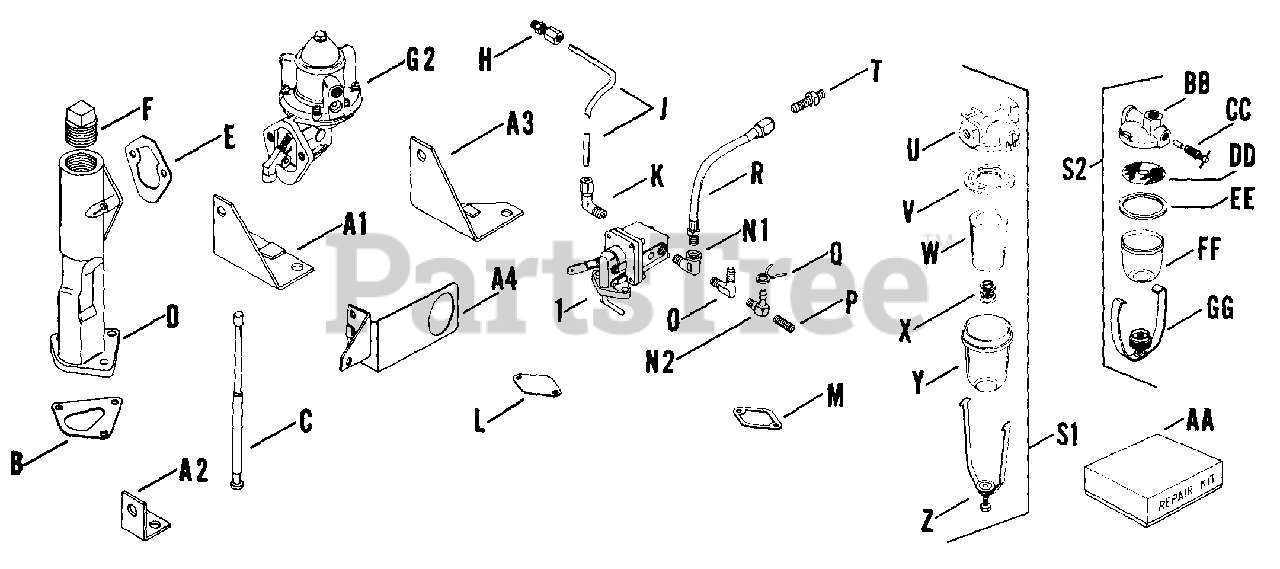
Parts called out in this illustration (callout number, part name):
K	Elbow, compression 1/8 I.P. x 1/4 tube
M	GASKET - USE 47 041 04
N1	ELBOW - USE 48 283 03
R	Line, flexible fuel 8
S1	FILTER - (#DSC)
V	GASKET - DISCONTINUED
W	ELEMENT - DISCONTINUED
X	SPRING - DISCONTINUED
Z	RETAINER - DISCONTINUED
AA	KIT, DIAPHRAGM - DISCONTINUED
